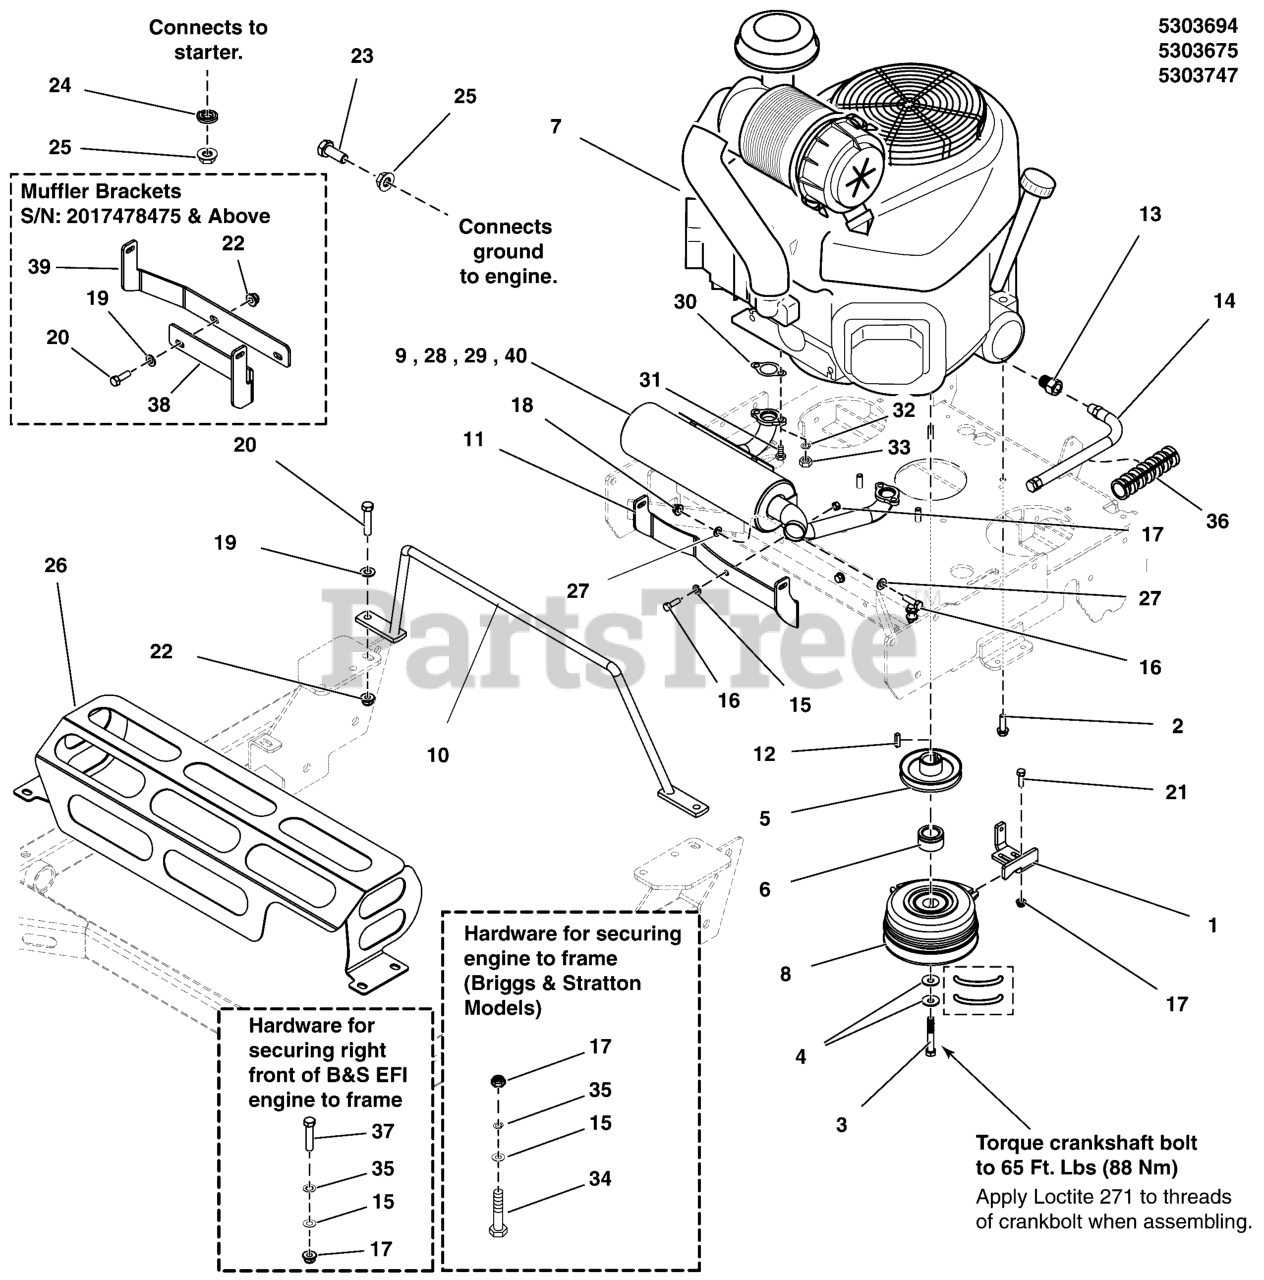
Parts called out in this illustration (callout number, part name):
1	PLATE, CLUTCH ANCHOR - BLK
2	BOLT, 3/8-16 X 1-1/4, SF, PLT W/PATCH
3	BOLT, CRANKSHAFT,7/16-20X2-3/4, GD8
4	BELLEVILLE WASHER 1.1875 X .442 X .089
5	PULLEY, CRANKSHAFT, 1.125ID X 4.50OD, OS
6	SPACER, 1.13 X 1.75 X 1.03, CZ
7	ENGINE
8	CLUTCH,5218-221, WARNER
9	MUFFLER, HORIZONTAL, KAWASAKI
10	WELD, MUFFLER GUARD - BLK
11	BRACKET, EXHAUST SYSTEM, WALK - BLK
12	KEY, 1/4 SQ X 1
13	ADAPTER-OIL DRAIN
14	HOSE, OIL DRAIN
15	WASHER, 5/16" SAE
16	BOLT, 5/16-18 X 1 GD5 YZ
17	NUT, 5/16-24, NYLOCK FLANGE, GD8, CZ
18	NUT, 5/16-18, HEX, CNTR LK,ZINC PHOS/OIL
19	WASHER, 3/8 SAE
20	BOLT, 3/8-16 X 1-1/4" GD5 CZ
21	BOLT, 5/16-18 X 1" CARRIAGE
22	NUT, 3/8-16 HEX NYLOCK FLANGE
23	BOLT, M8-1.25 X 20MM GD8.8
24	WASHER, 5/16 LOCK CZ
25	NUT, M8-1.25 SERR. FLANGE, CZ
26	WELD, CE MUFFLER GUARD, FW35 - RED
27	WASHER, HARD, F436
28	MUFFLER, 26/28, B&S VANG, TWR/WALK
29	MUFFLER, 26/28, B&S EFI, TWR/WALK
30	GASKET, EXHAUST
31	SCREW-HEX SEMS LOCK WSHR 5/16-18X0.875
32	WASHER, 5/16 LIGHT LOCK
33	NUT, 5/16-18 HEX
34	BOLT, 5/16-24 X 1-3/4, GD8
35	WASHER, 5/16 INT. TOOTH LOCK
36	LOOM, 3/4" ID X 8.00" LG
37	BOLT, 5/16-24 X 1-1/2, GD8, PHOS
38	PLATE, MUFFLER SUPPORT, LH, W35 - BLK
39	PLATE, MUFFLER SUPPORT, RH, W35 - BLK
40	MUFFLER, 15-19HP KAWI, CATALYTIC COMBUST
